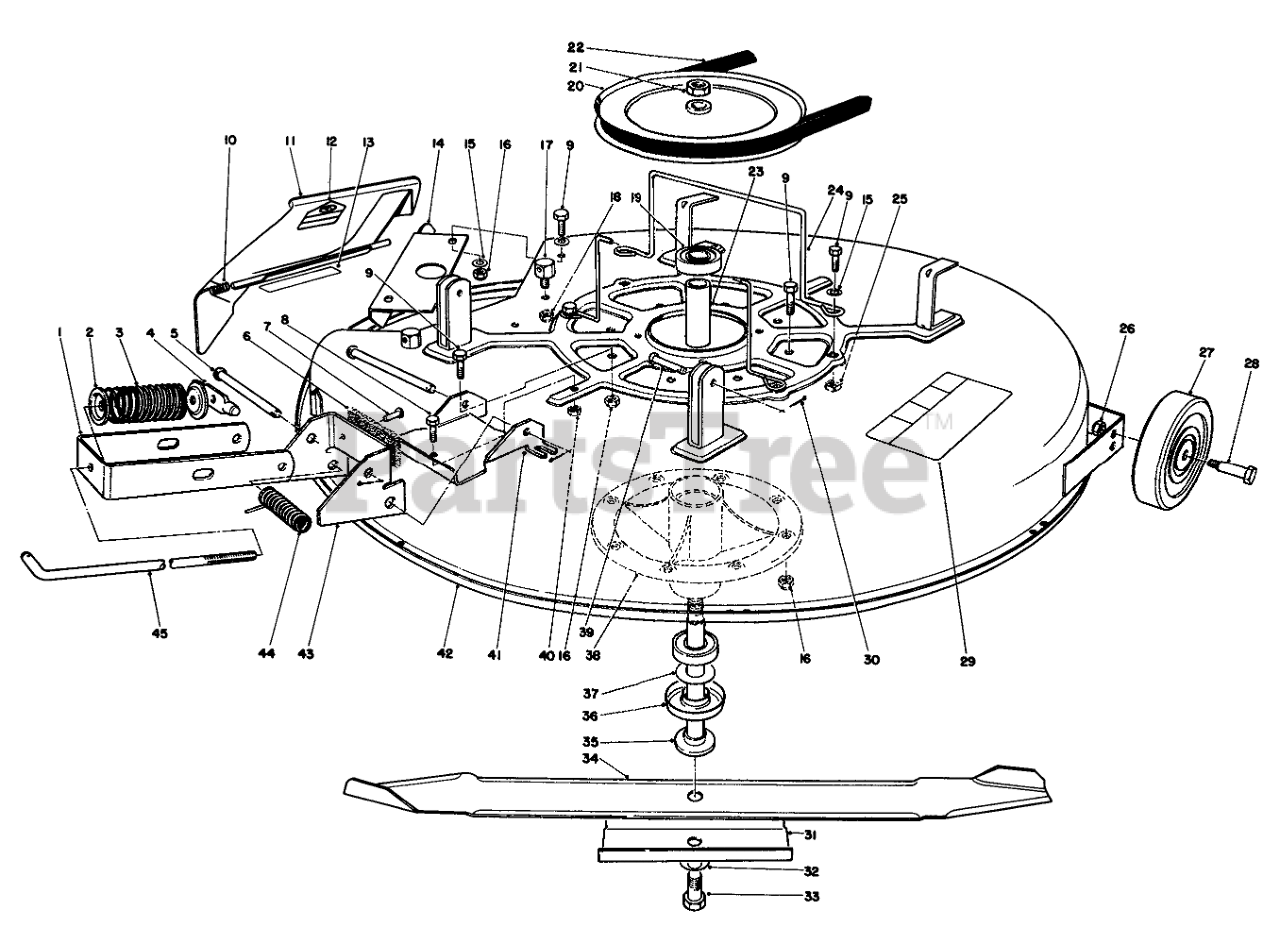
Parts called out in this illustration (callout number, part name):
1	Bracket-Engagement
2	RETAINER-SPR. TOP
3	SPRING-COMPRESSION
4	SHAFT-DECK ADJ.
5	PIN-CLEVIS
6	PAD-BRAKE
7	RIVET .187 X 7/16 BRASS
8	SCREW-HH
9	SCREW-HH
10	SPRING
11	Assembly-Deflector (Incl. Ref. #12)
12	DECAL-DANGER
13	DECAL-DANGER, DEFLECTOR
14	Baffle Deck
15	WASHER-PLAIN
16	NUT-LOCK, NI
17	POST-PIVOT
18	NUT-LOCK, SIDE
19	BEARING-BALL
20	PULLEY
21	NUT-HEX
22	V-BELT, DECK
23	SPACER-BEARING
24	GUIDE-BELT
25	NUT-RETAINER
26	NUT-LOCK, NI
27	WHEEL-DECK
28	BOLT-WHEEL
29	DECAL-DANGER, THROWN OBJECT
30	PIN-COTTER
31	STIFFENER
32	WASHER-BELLEVILLE
33	SCREW-HH
34	Blade
35	SHAFT-SPINDLE
36	SHIELD-BEARING
37	SPACER-HARDNED
38	SPINDLE
39	PIN-CLEVIS
40	NUT-HEX
41	Plate-Deck, Brake Mtg.
42	Deck-Cutting
43	Assembly-Brake (Incl. Ref. #6 & 7)
44	SPRING
45	ROD-ENGAGEMENT
